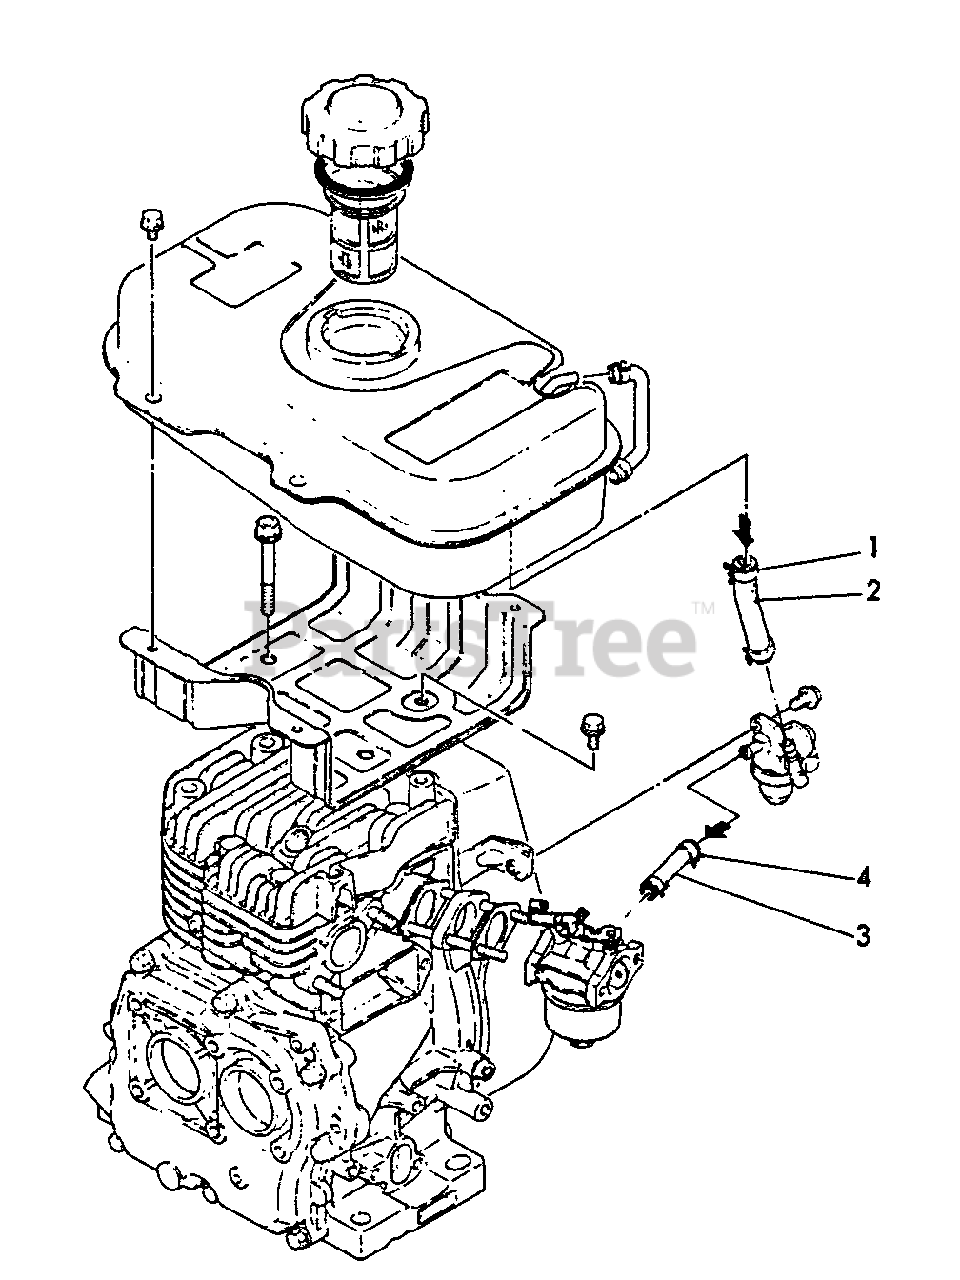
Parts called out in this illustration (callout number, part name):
1	CLAMP, HOSE
2	PIPE (A), FUEL
3	PIPE, FUEL
4	CLAMP
